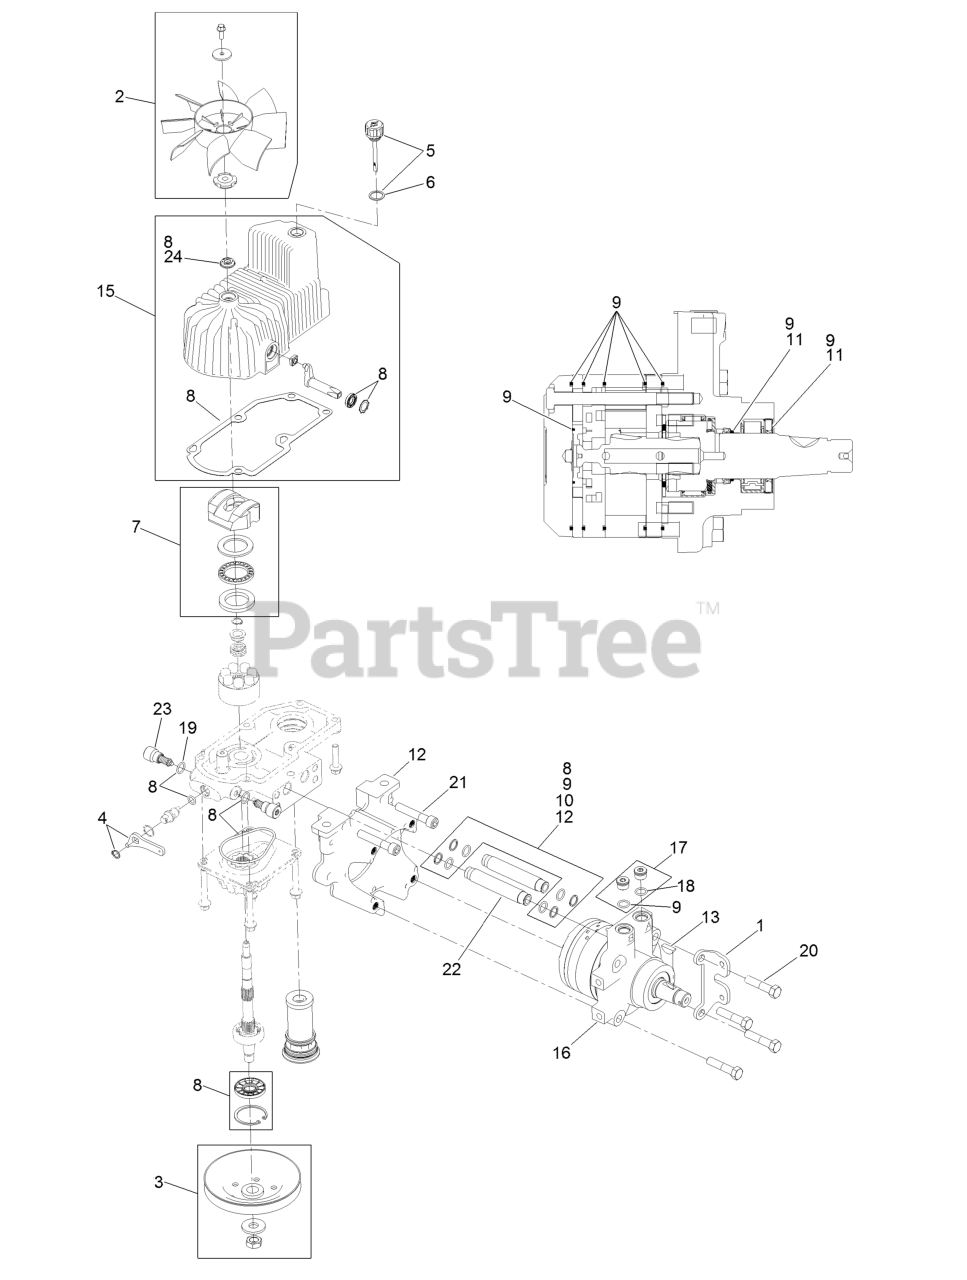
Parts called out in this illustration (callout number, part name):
1	Mount-Shoe, Horse
2	Fan Kit
3	Pulley Kit
4	Handle-Bypass Valve, Hydro
5	Dipstick-Hydro W/Gasket
6	Gasket-Dipstick, Hydro
7	Swash Block Kit
8	Pump Seal Kit
9	Motor Seal Kit
10	Tube Seal Kit
11	Output Shaft Seal Kit
12	Nose Cup-Uht
13	Key-Woodruff
15	Housing-RH
16	Motor-Hydraulic RH 240Cc
17	Magnetic Plugs Service Kit
19	O-Ring-Check Valve
20	Screw HH
21	Screw-HSH
22	Hydraulic Tube Kit
23	Shock Valve, 12Cc Hydro
24	Seal-Fan Drive
99	Puller-Pulley
99	Flow Test Kit
